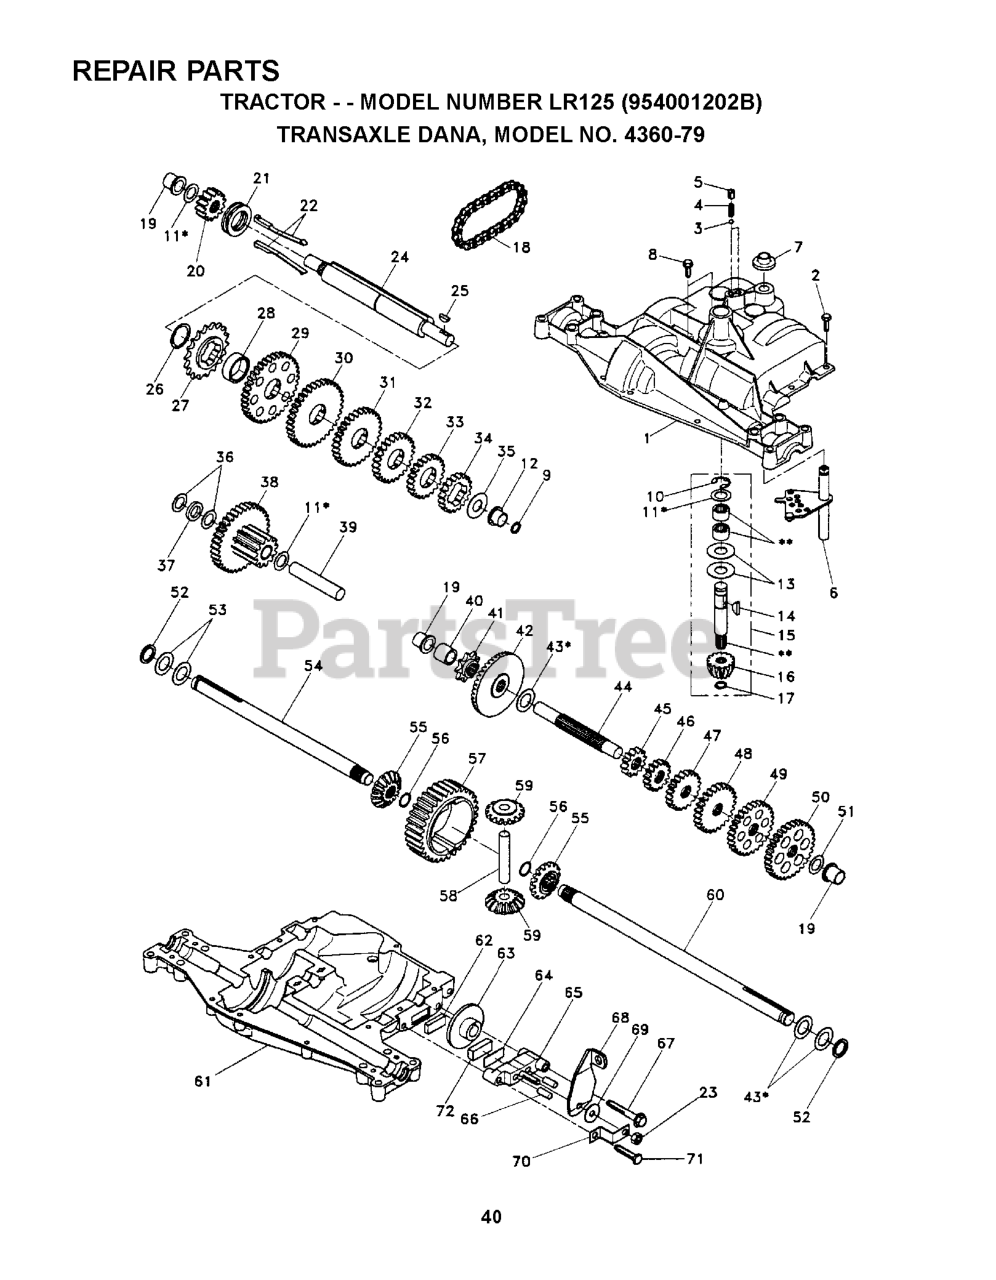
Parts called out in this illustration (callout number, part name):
1	HOUSING, UPPER
3	DETENT, BALL
4	SPRING, DETENT
6	SHIFTER KIT
7	BOOT, SHIFTER
8	SCREW, SELF TAPPING W/SEALER
9	SQUARE RING
10	RING, RETAINING
11	SHIM.KIT.DANA.4689
12	Bearing, Flange
13	WASHER.PLAIN..632X1.38X.046
14	KEY.WOODRUFF.DANA
15	AS KIT INPUT SHFT
16	PINION 14T
17	RING RETAINING
18	CHAIN 24 PITCH LT
19	BEARING, FLANGE LT
20	GEAR SPUR 14 TTH
22	ASSEMBLY KIT, CLUTCH KEYS
23	LOCKNUT
24	SHAFT INTERM DANA
25	KEY, WOODRUFF, #61
26	RING, RETAINING LT
27	SPROCKET 18T
29	GEAR, SPUR 37 TEETH
30	GEAR, SPUR 35 TEETH
32	GEAR, SPUR 25 TEETH
33	GEAR, SPUR 22 TEETH
36	WASHER 025
38	ASSM GEAR COMB T NLA
39	SHAFT IDLER
41	SPROCKET 9T LT
42	GEAR 42T
44	SHAFT, DRIVE
46	GEAR SPUR 15T DANA
49	GEAR, SPUR 28 TEETH
50	GEAR, SPUR 31 TEETH
52	NEOPRENE.WASHER.DANA
53	WASHER, PLAIN .758 X 1.25X.031
54	AXLE T, LH
55	GEAR 15T T
56	RING, RETAINING
59	GEAR 1ST T
61	LOWER HOUSING
62	PUCK, FRICTION
63	BRAKE DISC T
65	JAW T
67	SCREW, SELF TAPPING, LARGE
68	LEVER ACTUATOR
69	WASHER, PLAIN .321 X 1.00X.055
70	BRACKET, ANTI ROTATION
72	PUCK, FRICTION
73	SHELL, GREASE
